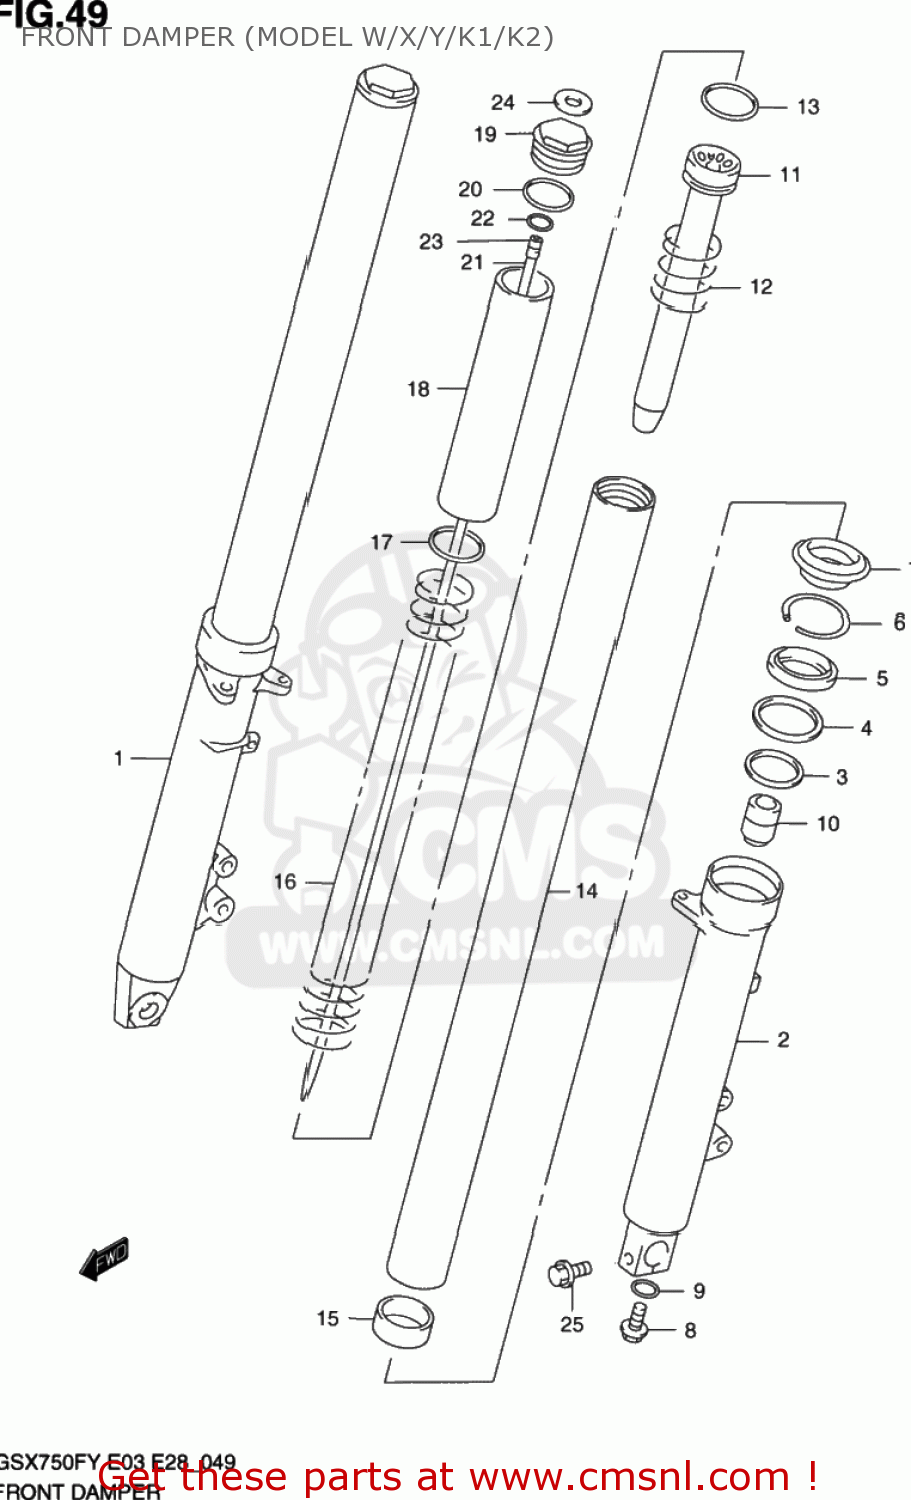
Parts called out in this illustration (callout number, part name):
1	TUBE,OUTER,R
2	TUBE,OUTER,L
3	BUSH,GUIDE
4	SPACER,SEAL
5	SEAL,OIL
6	CIRCLIP,FORK OIL SEAL
7	SEAL,DUST
8	BOLT(8X27)
9	GASKET (NAS)
10	PIECE,OIL LOCK
11	SEAT,UNDER
12	SPRING,REBOUND
13	RING,PISTON
14	TUBE,INNER
15	BUSH,SLIDE
16	SPRING,FR
17	JOINT,SPRING
18	COLLAR,SPRING
19	BOLT,FORK
20	O RING
21	ROD,DAMPER
22	O RING(D:1.9,ID:3.8)
23	RING,STOPPER(ID:6.1,D:0.6)
24	LABEL,S-H
25	BOLT
